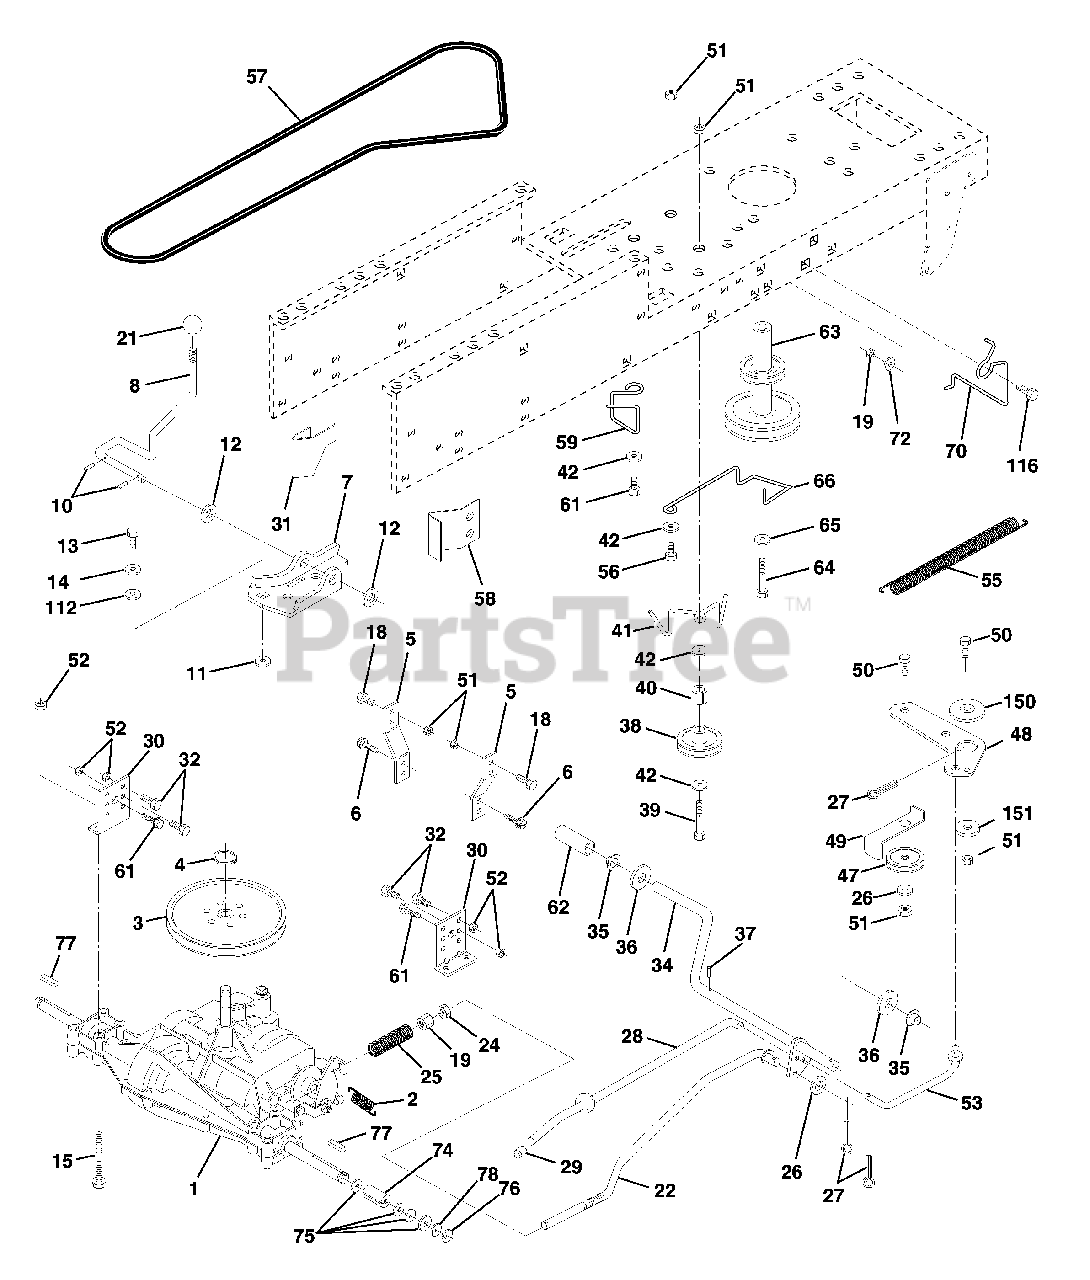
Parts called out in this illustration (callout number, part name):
1	Transaxle (See Breakdown) Dana
2	Spring Return Brake
3	Pulley Transaxle 18"tires
4	Ring Retainer # 5100-62
5	Strap Torque 30 Degrees
6	Screw Thdrol 5/16-18 X 3/4 TYT
7	Plate Rod Shift T/a
8	Rod Shifter Blk (Dana)
10	Pin Cotter 1/8 X 1 Cad
11	Washer Plate Shf 388 Sq Hole
12	Washer 15/32 X 3/4 X 16 Ga
13	Bolt 1/4-28 unf Gr. 8 w/Patch
14	Washer Lock Hvy Helical 1/4
15	Bolt Hex Flghd 5/16-18 Gr. 5
18	Bolt Fin Hex 3/8-16unc X 1 Gr. 5
19	Nut lock Hex w/Ins 3/8-16 Unc
21	Knob Duckhead 1/2-13 Unc Blk
22	Rod Brake LT
24	Nut Hex Jam 3/8-16 Unc
25	Spring Rod Brake 2 00 Zinc
26	Washer 13/32 X 13/16 X 16 Ga
27	Pin Cotter 1/8 X 3/4 Cad
28	Rod Brake Parking LT/YT
29	Cap Brake Parking Black
30	Bracket Transmission
31	Keeper Belt LH LT 14 Ga
32	Bolt Fin Hex 5/16-18 x 3/4
34	Shaft Asm Pedal Foot
35	Bearing Nylon Blk 629 Id
36	Washer 21/32 X 1 X 16 Ga
37	Pin Roll 3/16 X 1"
38	Pulley Idler Flat
39	Bolt Fin Hex 3/8-16unc X 2-3/4
40	Spacer Split 395 X 59 Bzp
41	Keeper Belt Idler
42	Washer 13/32 X 13/16 X 12 Ga
47	Pulley Idler V Groove Plastic
48	Bellcrank Clutch Grnd Drive STL
49	Retainer Belt Style Spring
50	Bolt Hex Hd 3/8-16unc X 1-1/2
51	Nut Crownlock 3/8-16 Unc
52	Nut Crownlock 5/16-18 unc
53	Link Clutch 7 66
55	Spring Return Clutch 6 75
56	Bolt Fin Hex 3/8 X 16 x 1-1/4
57	V-Belt Ground Drive 95 30
58	Keeper Belt RH LT Pnt/zinc 16g
59	Keeper Belt Chassis Span Ctr
61	Screw Thdrol 3/8-16x3/4 Ty-tt
62	Cover Pedal Blk Round
63	Engine Pulley LT/YT
64	Bolt Hex 7/16-20x4 Gr 5
65	Washer Lock Hvy Hlcl Spr 7/16
66	Keeper Belt Engine
70	Guide Belt Mower Drive RH
72	Washer 13/32 X 1-1/4 X 12 Ga
74	Spacer Axle
75	Washer 25/32 X 1 1/4 X 16 Ga
76	E-ring #5133-75
77	Key Square 2 0 X 1845/ 1865
78	Washer 25/32 X 1-5/8 X 16 Ga
112	Washer 9/32 X 3/4 X 10 Ga
116	Bolt Rdhd Sq Neck 3/8-16 x 1.25
149	Spacer Retainer PM Mower
150	Bushing Nylon Collered
151	Washer 13/32 x 2 x 10 Ga.
